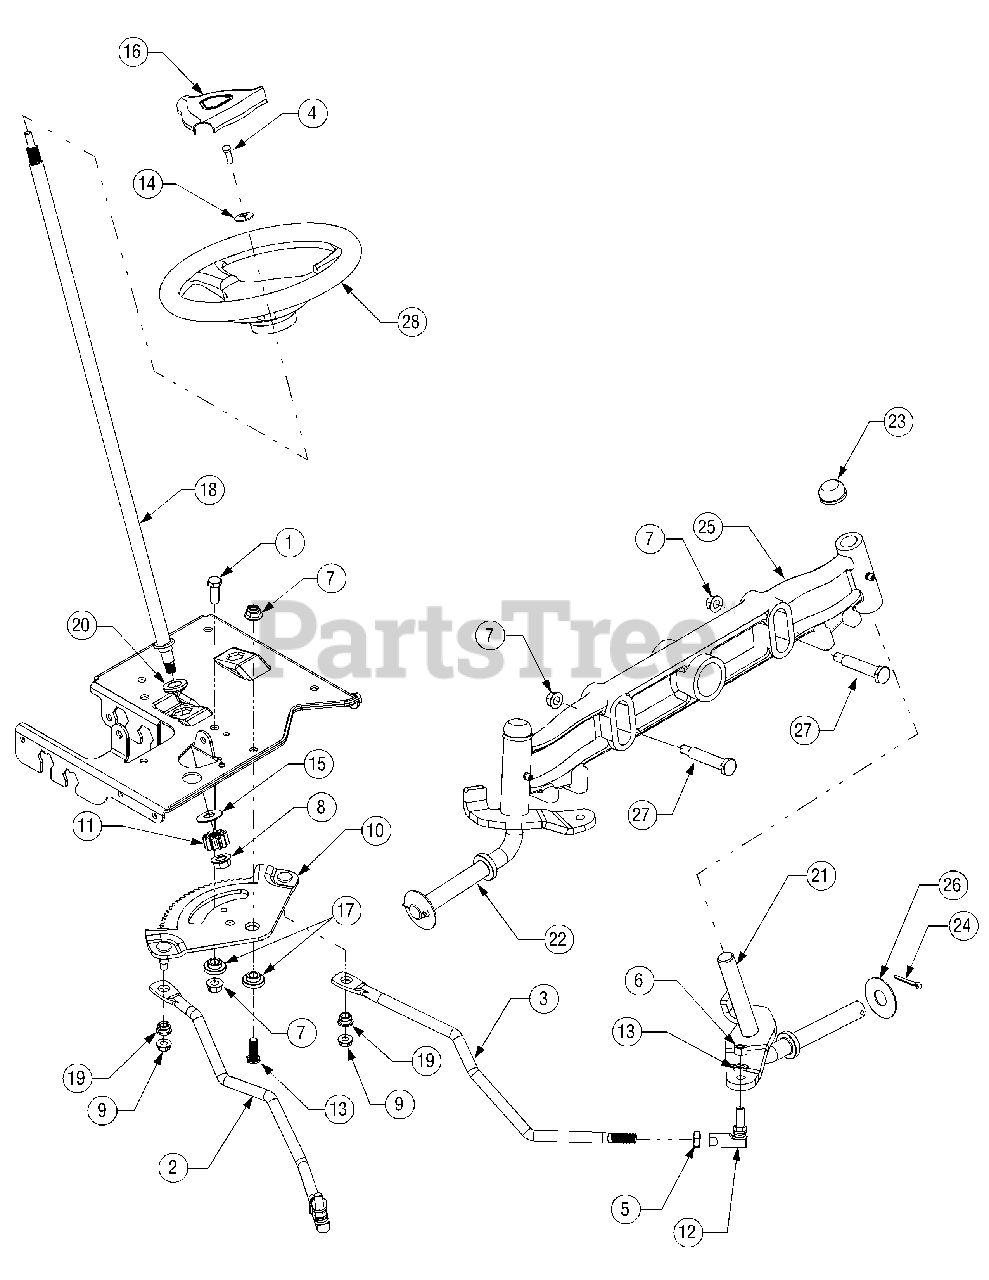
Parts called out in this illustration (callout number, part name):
1	Hex Cap Screw, 3/8-16, 1.00, Gr5, Std
2	Link, Drag, RH
3	Link, Drag, LH
4	Self-tapping Screw, 5/16-18 x .75
5	Nut, Jam, 7/16-20, Gr2
6	Nut, Hex, 3/8-24, Gr5
7	Nut, Nylon Lock, 3/8-16
8	Nut, Flange Lock, 7/16-20
9	Nut, Flange Lock, 5/16-18
10	Gear, Steering, 11/90 Ratio
11	Gear, Pinion, Steering
12	Ball Joint, 7/16-20
13	Hex Cap Screw, 3/8-16, 1.00
14	Washer, Flat, .406 x .875 x .105
15	Washer, Flat, .510 x 1.120 x .060
16	Cover, Steering Wheel
17	Spacer, Shoulder, 1.00 x .38 x .38
18	Shaft, Steering, .625 OD x 25.00 Lg
19	Bushing, Plastic, .380 ID
20	Bearing, Hex Flange, 5/8
21	Axle Ass’y, LH .750 Dia
22	Axle Ass’y, RH .750 Dia
23	Push Cap, .75
24	Pin, Cot, 5/32, 1.25
25	Axle, Pivot, Cast .750 Dia
26	Washer, Flat, .755 x 1.92 x.060
27	Screw, Shoulder, .500 x 2.230, 3/8-16
28	Wheel, Steering, Three Spoke
